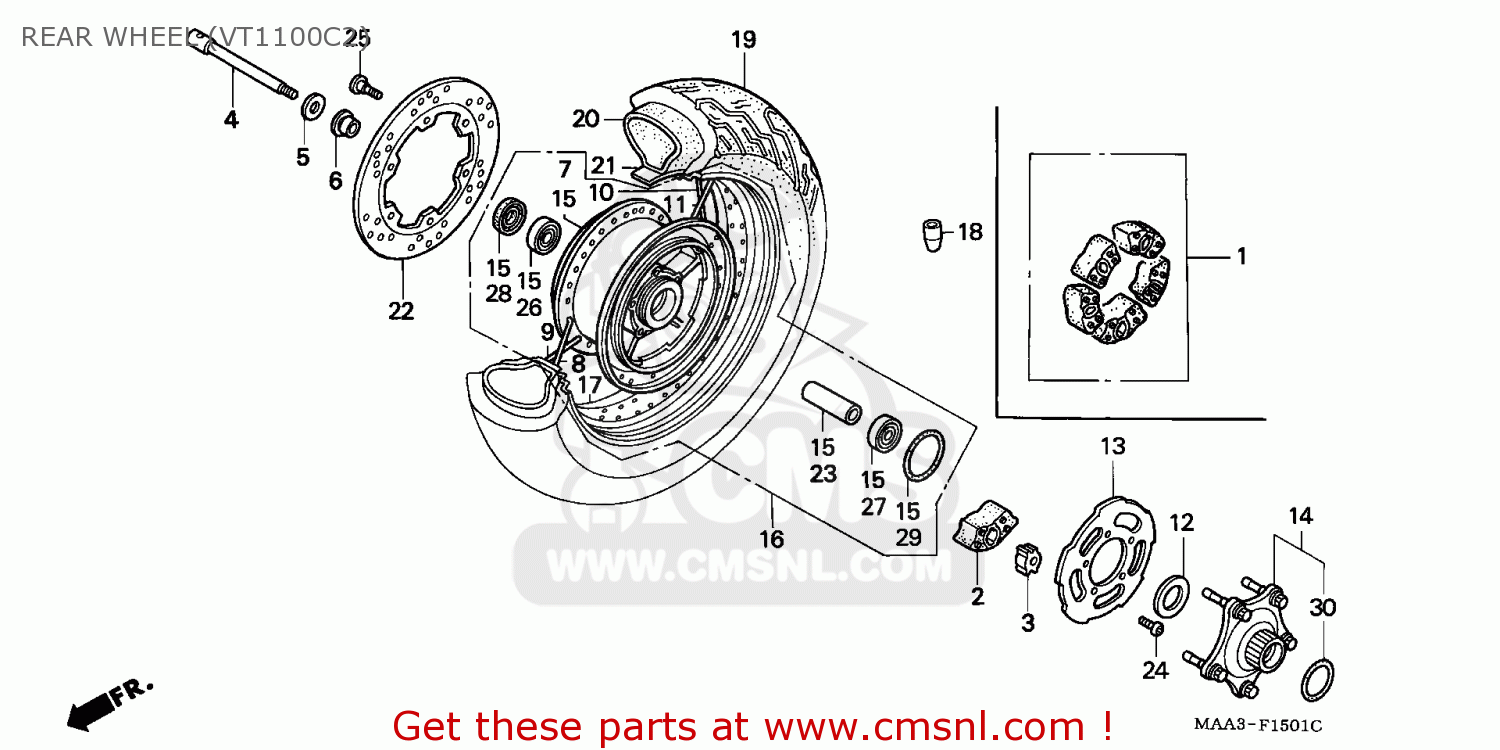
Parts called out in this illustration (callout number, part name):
2	DAMPER,RR WHEEL
3	PIECE DAMPER WHEE
4	AXLE,RR.WHEEL
5	SPACER RR BRK
6	COLLAR IRR BRKPNL
7	HUB,RR WHEEL
8	SPOKE SET,R RR IN
9	SPOKE SET,R RR OU
10	SPOKE SET,L RR IN
11	SPOKE SET,L RR OU
12	WASHER,THRUST
13	HOLDER,DAMPER
14	FLANGE SET,FINAL
16	WHEEL SUB ASSY,RR
17	RIM,RR WHEEL
18	WEIGHT,BALANCER (
19	TIRE,RR (US DUN)
20	TUBE,TIRE
21	FLAP,TIRE
22	DISK,RR BRAKE
23	COLLAR,FR.AXLE DI
24	BOLT,DISK,6X17
25	BOLT,BRK DISK 8X24
26	BEARING,BALL RADI
27	B/BRG N/RAD N/COM
28	DUST SEAL,30X47X8
29	O-RING,61X2
30	O-RING,46.5X3.5
